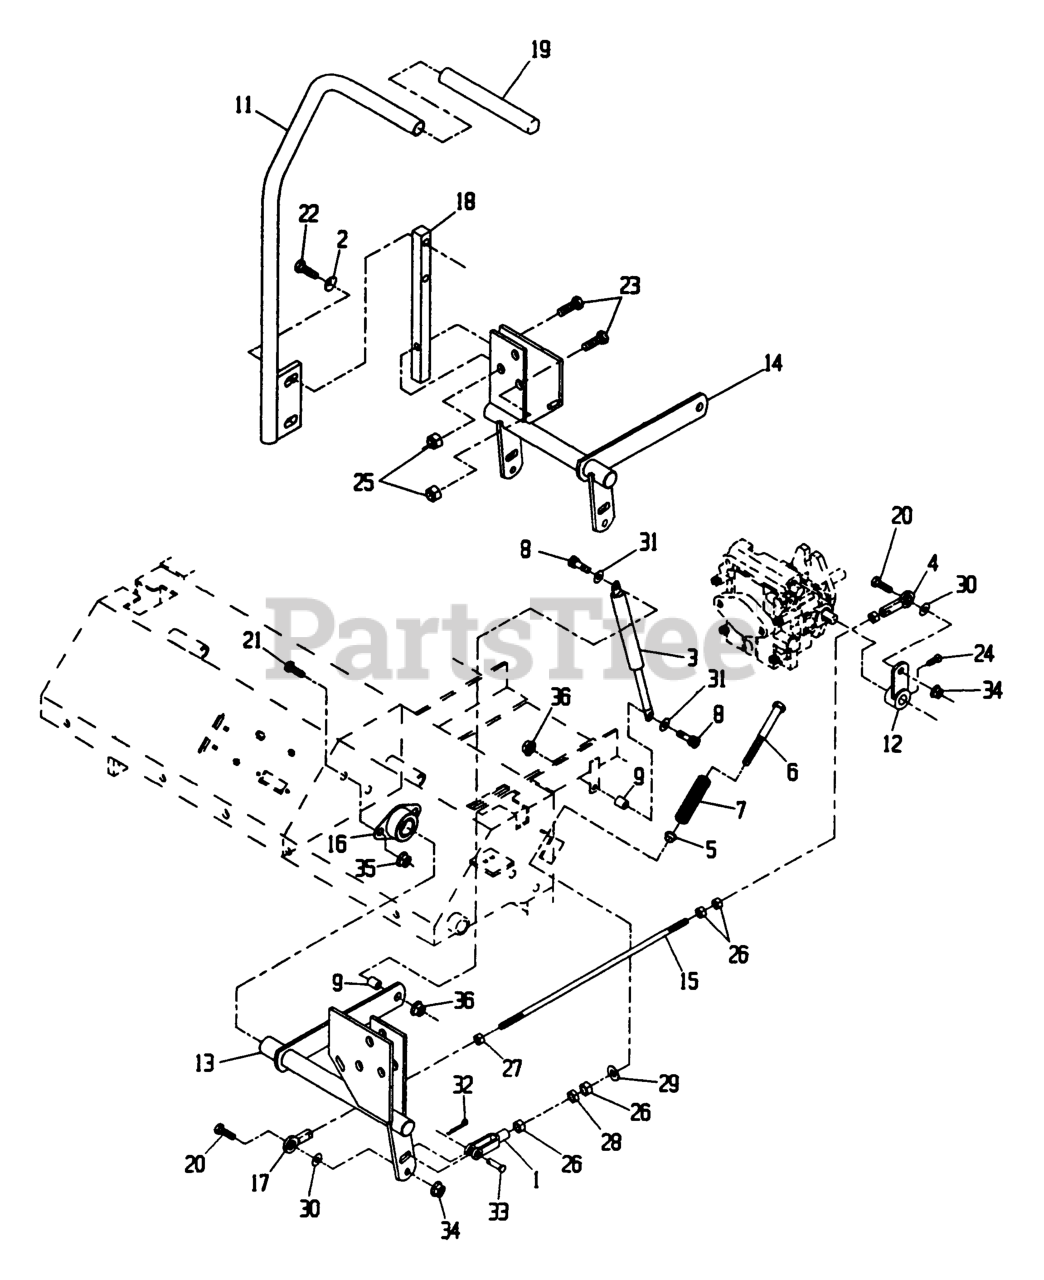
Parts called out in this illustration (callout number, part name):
1	YOKE-ADJUSTABLE
4	BALLJOINT-RH
5	BUSHING-FLANGED
6	BOLT-RETURN, NEUTRAL
7	SPRING-RETURN, NEUTRAL
8	SCREW-HSH
16	BEARING-FLANGE, SIDE
17	BALLJOINT-LH
18	ARM-CONTROL, SHAFT
19	GRIP-CONTROL, MOTION
24	SCREW-SET
33	PIN-CLEVIS
